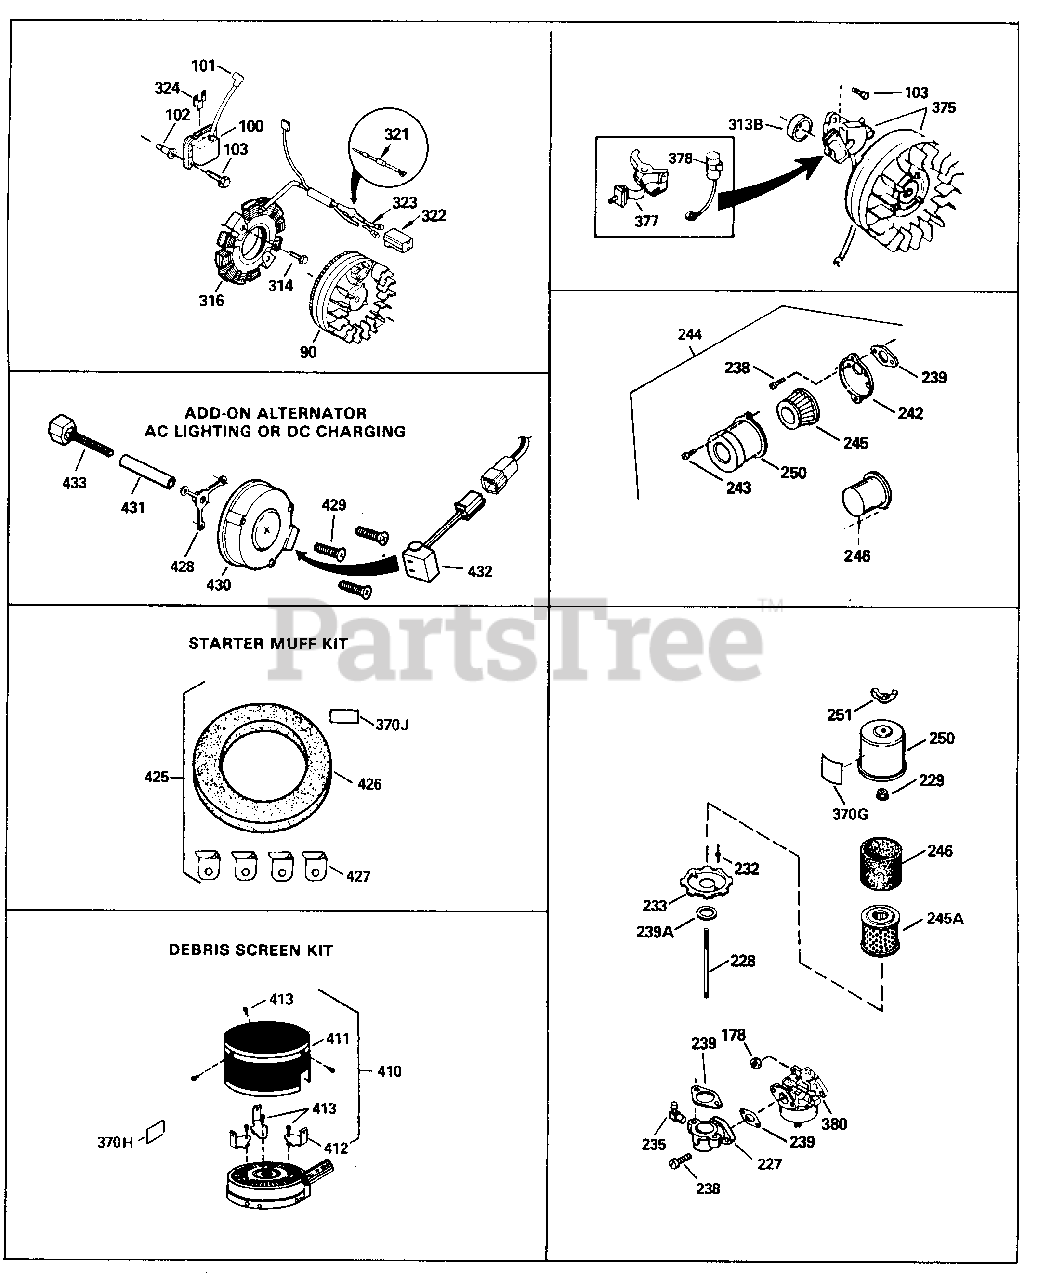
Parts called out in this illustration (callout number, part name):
90	Flywheel (w/ring gear)
100	Solid State Ass'y.
101	Cover, Spark plug
102	Stud, Solid state mounting
103	Screw, Torx T-15, 10-24 x 1"
178	Nut & Lock Washer 1/4-28
244	Air Cleaner Ass'y. (Incl. 238, 239, 2 42, 243, 246 & 250) (Use as required)
244	Air Cleaner Ass'y. (Incl. 238, 239, 2 42, 243, 245 & 250) (Use as required)
370H	Decal, Instruction (Optional)
370J	Decal, Instruction (optional)
380	Carburetor (Incl. 184) (Similar to 63 2113A except has no bowl drain; refer to Division 5, Section A, page A1-2 or Fiche 14A, Grid E-1 for breakdown)
410	Opt.Screen Kit Incl. 370H, 411, 412 & 413
411	Debris Screen (Optional)
412	Debris Screen (Optional)
413	Screw, 8-32 x 1/4" (Optional)
425	Starter Muff Kit (Incl. 426,427,370J) O pt.
426	Air Cleaner, Starter (Optiona)
427	Bracket, Starter air cleaner Optiona l
428	Spacer (Use as required)
429	Screw (3 required) (Use as required)
430	Alt. AC lighting/DC charging As req.
431	Centering tube (Use as required)
432	A.C. Lighting Connector Use as requir ed
432	D.C. Charging Connector Use as requir ed
433	Alternator Shaft (Use as required)
999	Winter Maintenance Kit incl. 5W30 Oil , Spark Plug, Key, & Ultra-Fresh
999	Winter Maintenance Kit (incl. 0W30 Sy nthetic Oil, Spark Plug, Key, & Ultra -Fresh)
